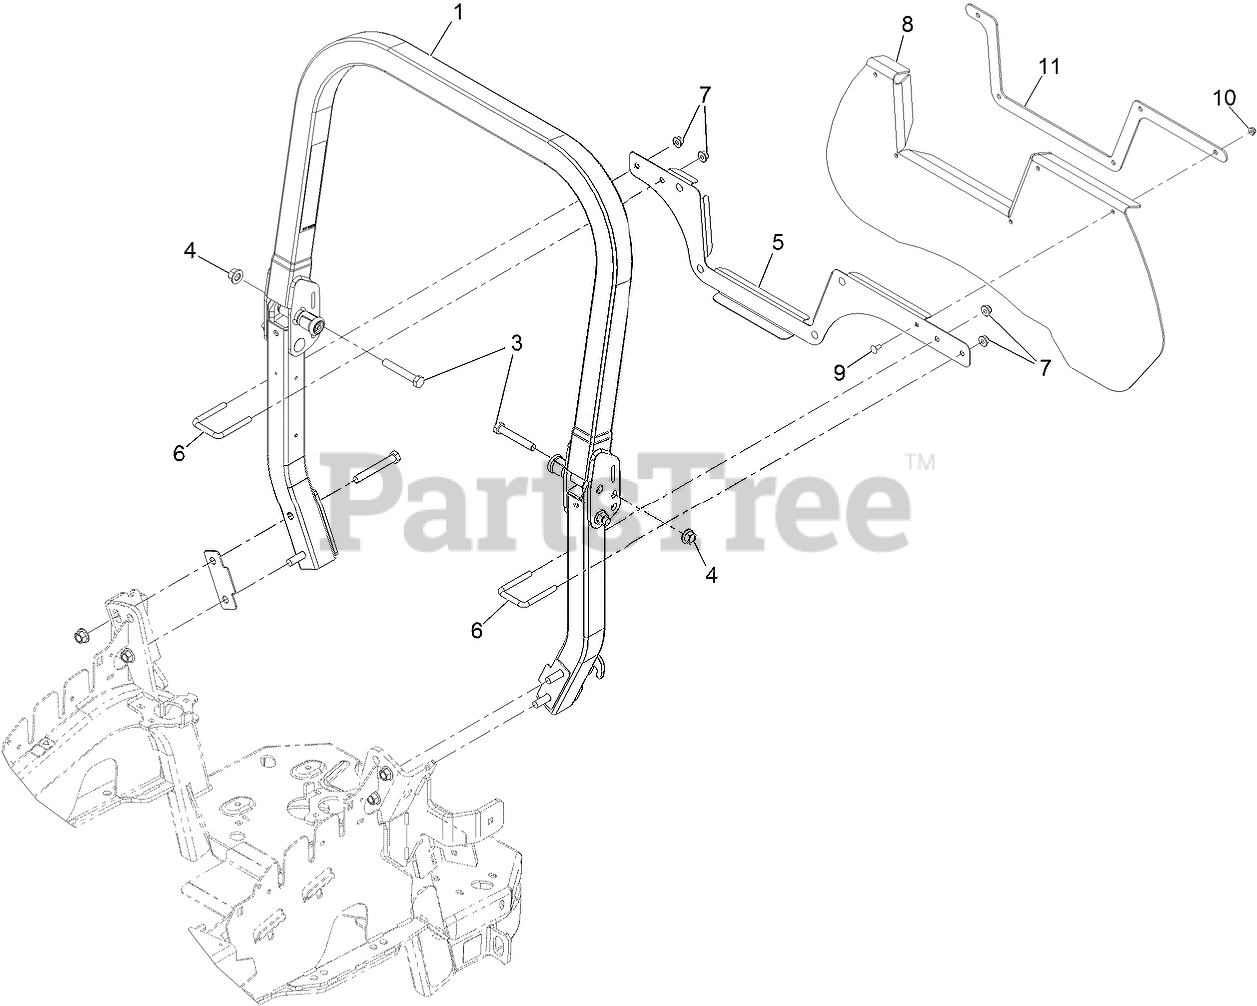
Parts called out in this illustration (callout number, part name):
1	ASM,ROPS SERVICE EXMARK
3	SCREW-HH
4	Nut-Lock 1/2-13
5	Bracket-Air Dam
7	NUT-HF, NI
11	Plate-Backer Air Dam
